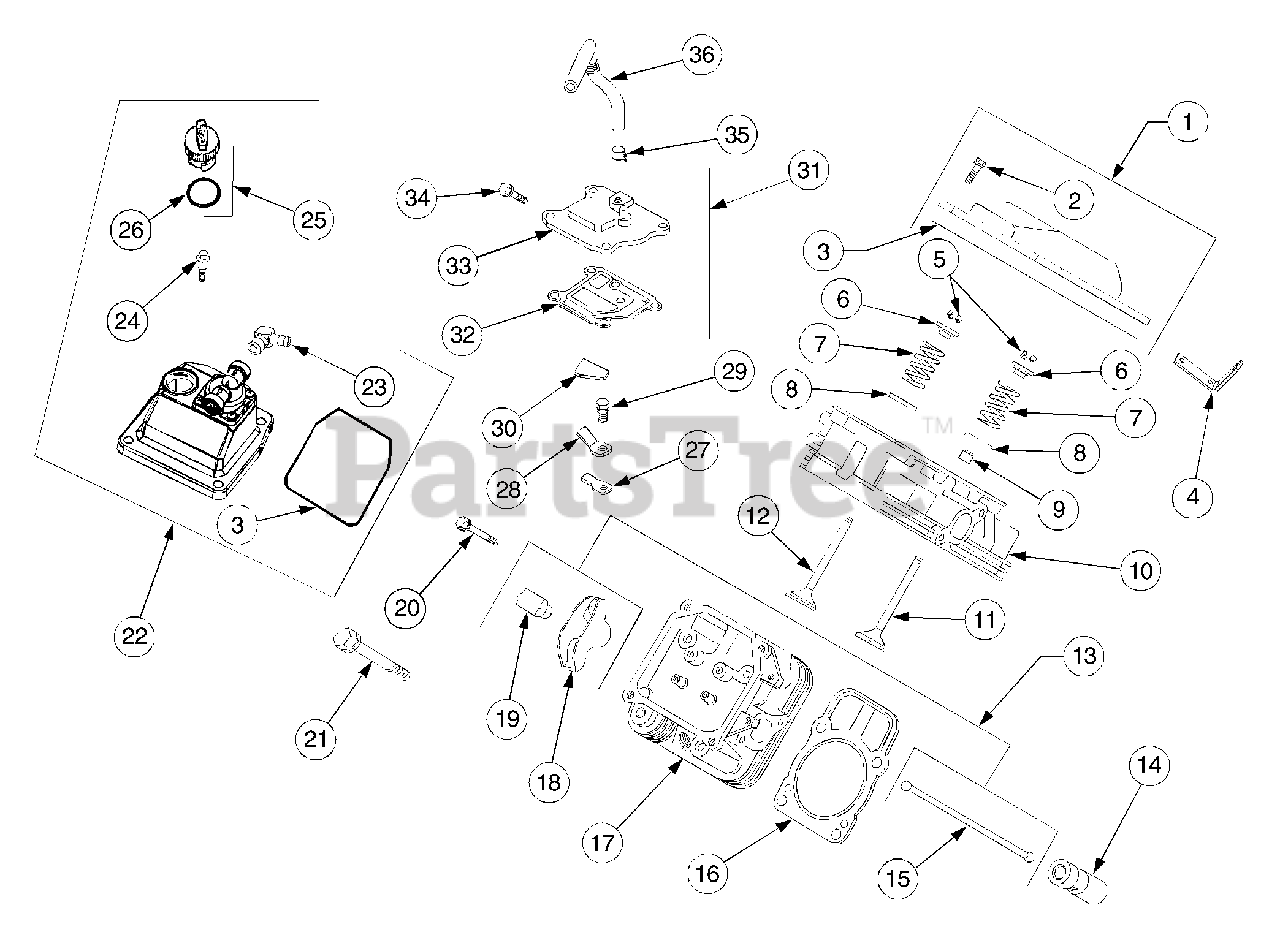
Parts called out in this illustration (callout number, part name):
1	Kit , Valve Cover
2	Screw, Hex Flng, M6 x 1.0 x 30
3	O-Ring, Valve Cover
4	Strap, Lifting
5	Kit, Retainer
6	Cap, Valve Spring
7	Spring, Valve
8	Retainer, Spring
9	Seal, Valve Stem
10	Head Assembly, #1 Cylinder
11	Valve, Intake Std
12	Valve, Exhaust Std
13	Kit, Valve Train
14	Lifter, Valve
16	Kit, Cyl. Hd. Gasket
17	Head Assembly , #2 Cylinder
19	Pivot, Rocker Arm
20	Screw, Hex Flng, M6 x 1.0 x 34
21	Screw, Hex Flng, M10 x 1.5 x 90
22	Kit , Fuel Pump Valve Cover
23	Fitting, 90°.
24	Screw, Shoulder
25	Cap Assembly, Oil Fill
26	O-Ring
27	Reed, Breather
28	Retainer, Breather Reed
29	Screw, Hex Flng, M5 x 0.8 x 10
30	Filter, Breather
31	Kit, Breather
32	Gasket, Breather
33	Cover, Breather
34	Screw, Hex Flng M6 x 1.0 x 20
35	Clamp, Breather
36	Hose, Breather
